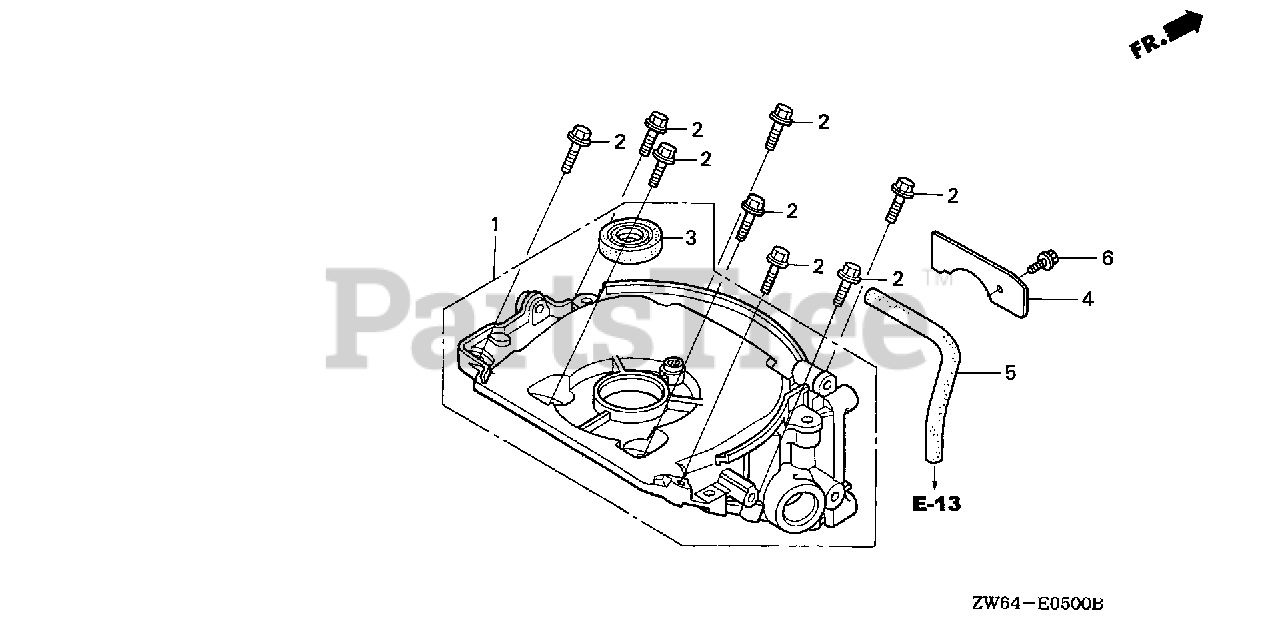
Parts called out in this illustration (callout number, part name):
1	CASE ASSY., OIL
2	BOLT, FLANGE (5X23) (CT200)
3	OIL SEAL (17X27X5) (KOYO)
4	PLATE, TUBE SETTING
5	TUBE, CLUTCH HOUSING BREATHER
6	BOLT, FLANGE (5X10) (CT200)
